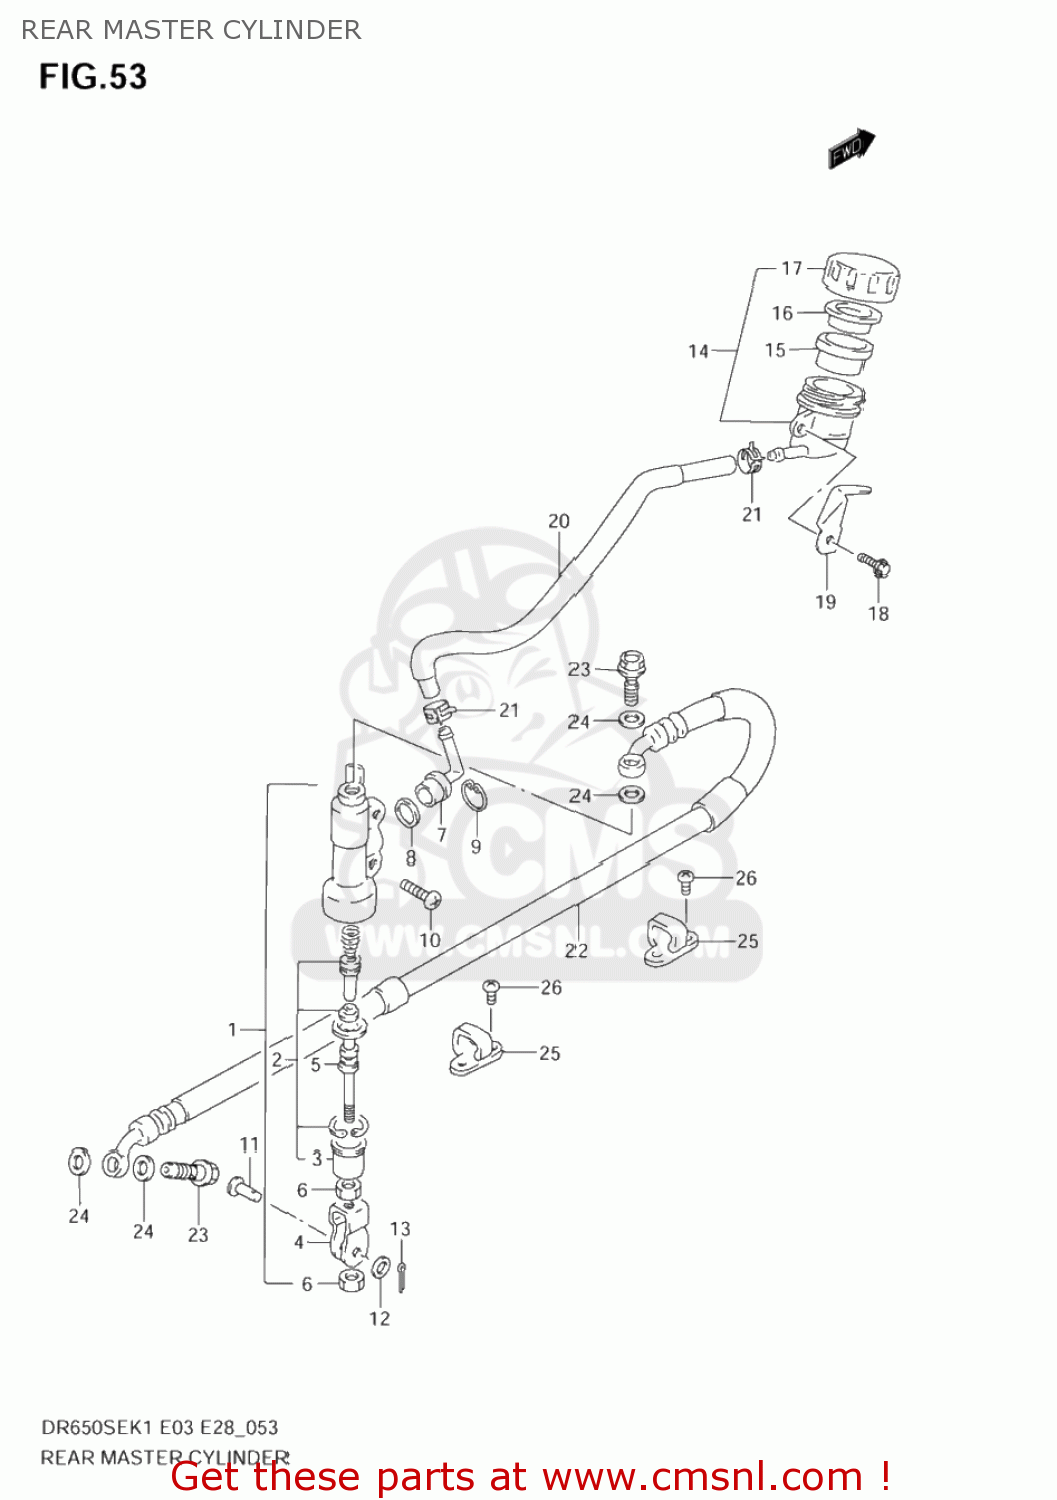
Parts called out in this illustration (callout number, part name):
1	CYLINDER ASSY,RR MASTER
2	PISTON/CUP SET
3	BOOT
4	YOKE
5	ROD,PUSH
6	NUT
7	CONNECTOR
8	O RING
9	CIRCLIP
10	SCREW(6X16)
11	PIN(8X20)
12	WASHER (8.5X14X1.6)
13	PIN
14	TANK ASSY,RR BRAKE RESERVOIR
15	DIAPHRAGM
16	PLATE
17	CAP
18	BOLT
19	GUARD,RSVR TANK CAP
20	HOSE,RESERVOIR TANK
21	CLIP
22	HOSE COMP,REAR BRAKE
23	BOLT UNION
24	WASHER(10X15X1.5)
25	GUIDE,RR BRAKE
26	SCREW
